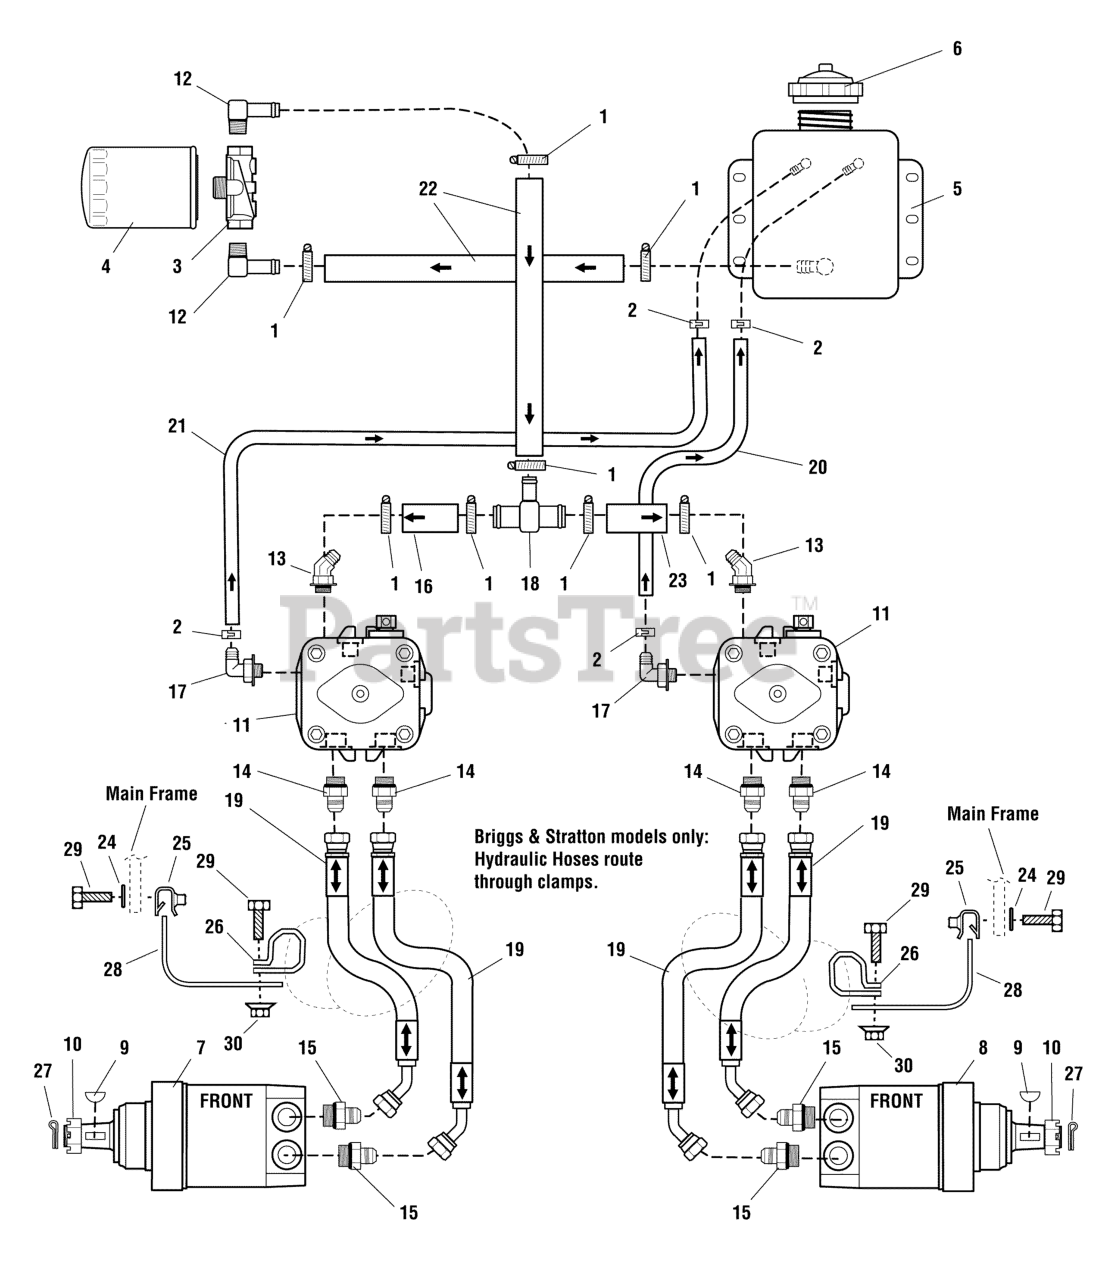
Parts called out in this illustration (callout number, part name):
1	CLAMP, #10 HOSE STAINLESS
2	CLAMP, HOSE
3	FILTER HEAD
4	FILTER, HYDRAULIC, SERVICE PART (PKG)
5	KIT, TANK HYDRAULIC, 3QT W/ FITTINGS
6	CAP, HYDRAULIC RESERVOIR
7	* MOTOR, WHEEL REAR PORT LH 15CI
8	* MOTOR, WHEEL REAR PORT RH 15CI
9	KEY
10	CASTLE NUT
11	** HYDRAULIC PUMP W/ FAN (SV)
11	7" FAN HUB ASSEMBLY (SV)
11	KIT, OVERHAUL SEAL
11	SEAL, OUTPUT SHAFT, 17 X 40 X 7 (SV)
12	FITTING, 1/2NPT-5/8" HOSE, 90 DEG
13	FITTING, 5/8 TUBE TO #8 O-RING, 45 ELBOW
14	ADAPTER, HYDRAULIC
15	ADAPTER, HYDRAULIC
16	HOSE, 5/8 PUSH-LOCK, 6.00"
17	ADAPTER, 90 DEG, 9/16-3/8 BARB
18	TEE, HYDRAULIC, BEADED HOSE, 5/8 X 5/8 X 5/8
19	HOSE ASSEMBLY, (33)
20	HOSE, 3/8" PUSH-LOCK, 12.00"
21	HOSE, 3/8" PUSH-LOCK, 17.50"
22	HOSE, 5/8" PUSH-LOCK, 11.50"
23	HOSE, 5/8" PUSH-LOCK, 8.50"
24	WASHER, 5/16" SAE
25	BODY CLIP, 5/16-18-7GA MATERIAL
26	VINYL CLAMP
27	COTTER PIN
28	PLATE, HOSE ANCHOR
29	BOLT, 5/16-18 X 1" GD5 YZ
30	NUT, 5/16-18 HEX SERRATED FLANGE (SMALL)
